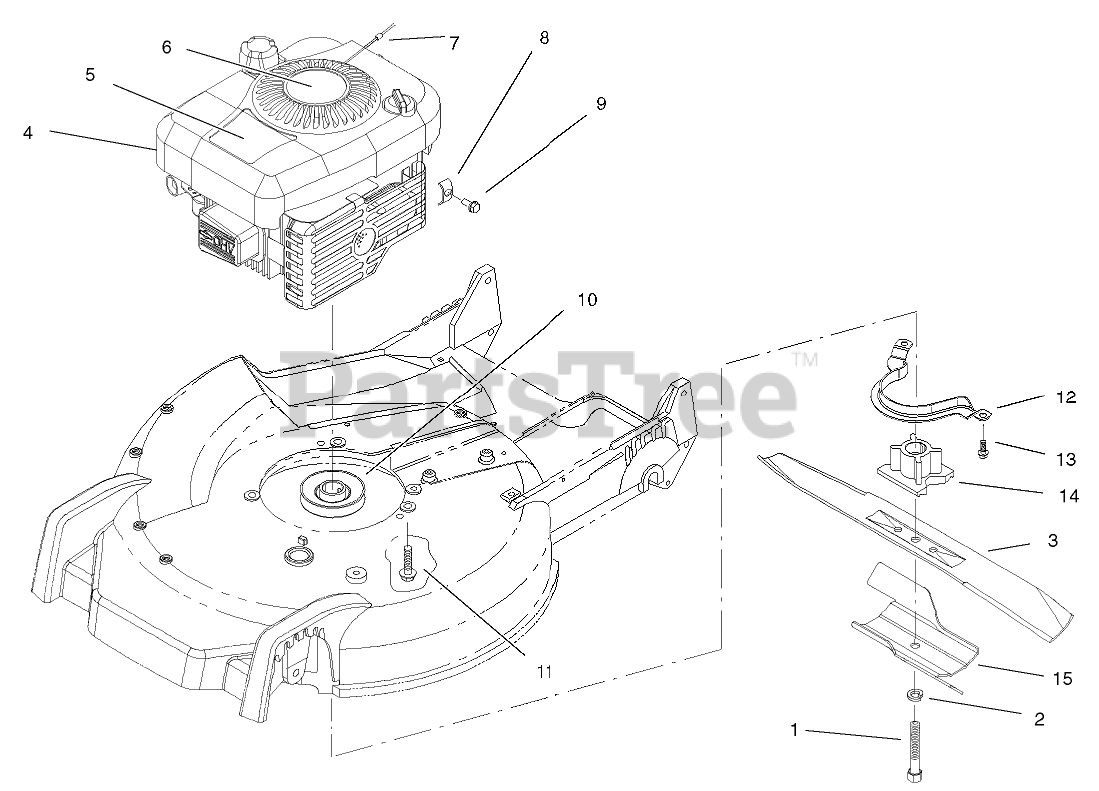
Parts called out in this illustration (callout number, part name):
1	SCREW-BLADE
2	WASHER-LOCK
3	BLADE
4	Engine-Gts
5	PLATE-LOGO
6	DECAL - RECOIL
7	STOP-ROPE
8	CLAMP
9	BOLT (5X18)
10	PULLEY ASM
11	SCREW-MOUNT, ENGINE
12	GUIDE-BELT
13	SCREW-HWHTF
14	RETAINER - BLADE
15	ACCELERATOR-BLADE
